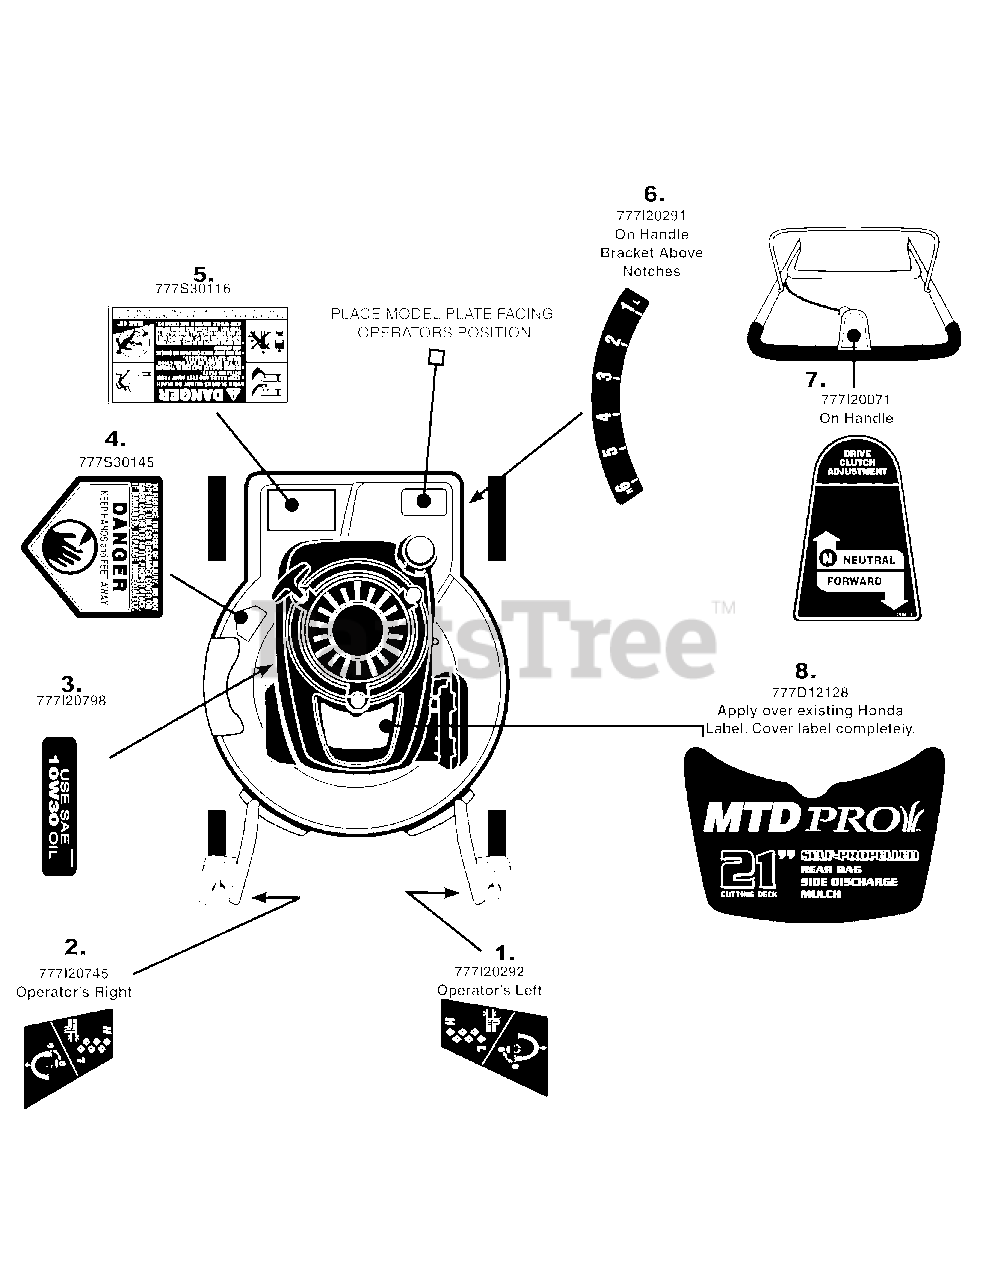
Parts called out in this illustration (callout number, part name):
1	LABEL-CASTOR LOCK
2	LABEL-CASTOR LOCK
3	LABEL-SHROUD
4	LABEL
5	LABEL-MOWER DANGER
6	LABEL-HEIGHT ADJUS
7	LABEL-SELF PROPELL
8	LABEL-MOWER SHROUD MTD PRO 21" SP
